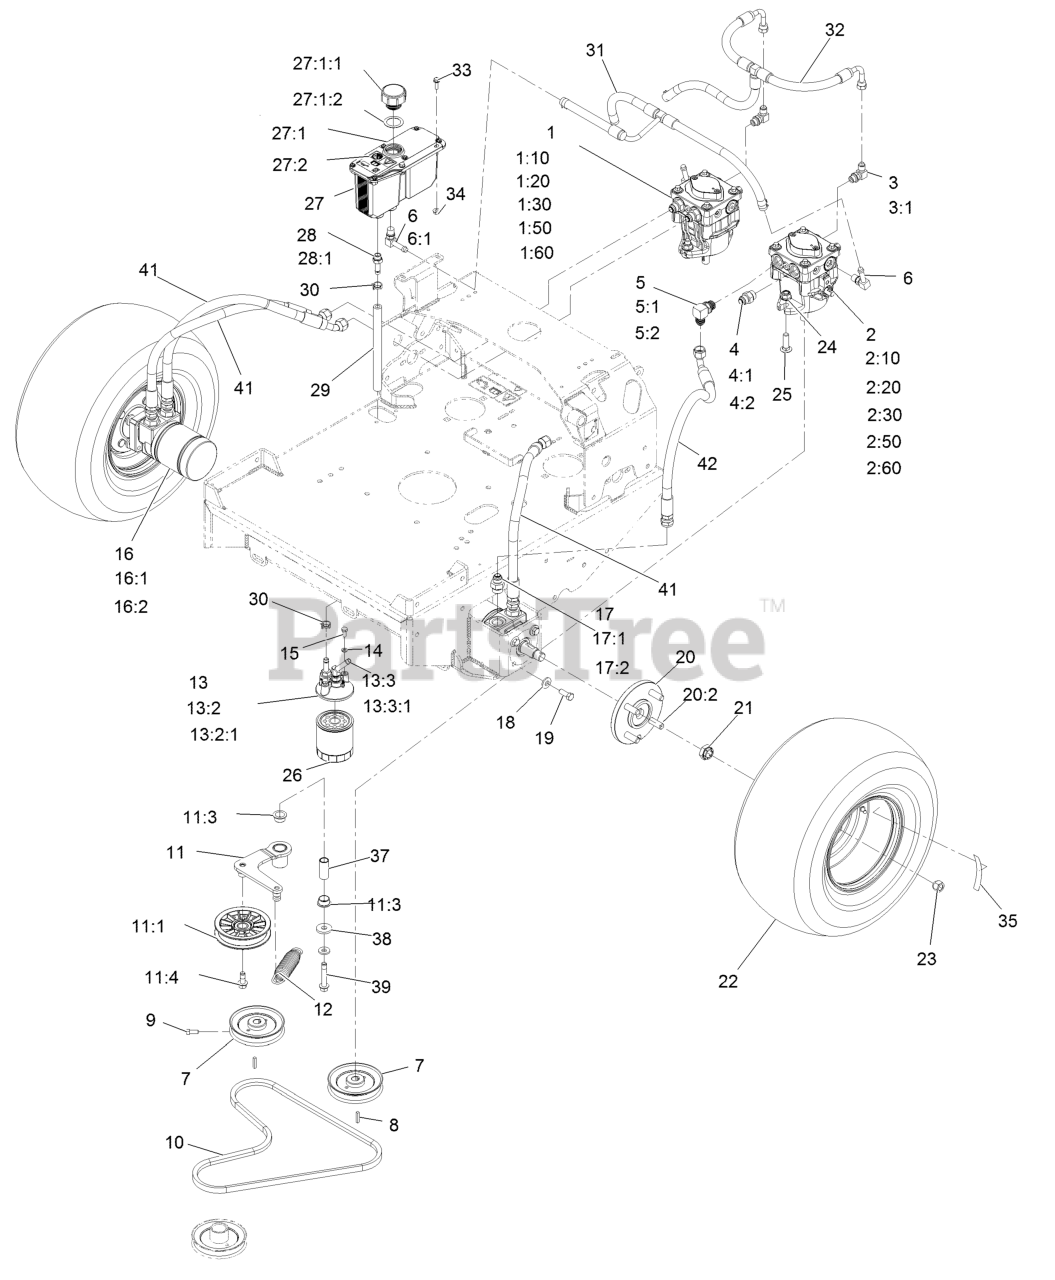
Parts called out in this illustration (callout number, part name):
1	PUMP-HYD PE RH TTH
1:10	INPUT SHAFT KIT
1:20	BEARING-THRUST
1:30	CYLINDER BLOCK KIT
1:50	SEAL OVERHAUL KIT
1:60	KIT, 10CC PUMP KIT
2	PUMP-HYD PE LH TTH
2:10	INPUT SHAFT KIT
2:20	BEARING-THRUST
2:30	CYLINDER BLOCK KIT
2:50	SEAL OVERHAUL KIT
2:60	KIT, 10CC PUMP KIT
3	FITTING-ELBOW, 90 DEG
4	FITTING-STRAIGHT
5	FITTING-90 DEG
6	FITTING-ELBOW, 90
6:1	O-RING
7	SHEAVE ASM
9	SCREW-SET, SQH
10	BELT
11	ASM, PUMP IDLER
11:1	PULLEY-IDLER, FLAT
11:3	BUSHING-FLANGE
11:4	SCREW-HFH
12	SPRING-EXTENSION
13	ASM, FILTER HEAD
13:2	ADAPTER-STRAIGHT
13:2:1	O-RING
13:3	FITTING-BARBED, 45 DEG
13:3:1	O-RING
14	WASHER-LOCK
15	SCREW-HH
16	HYD MOTOR ASM
16:1	SEAL KIT
16:2	BEARING AND SEAL KIT
17	FITTING-STRAIGHT
17:1	O-RING
18	WASHER-BELLEVILLE
19	SCREW-HH
20	WHEEL HUB ASM
20:2	STUD-WHEEL
21	NUT-LOCK
22	ASM, DRIVE TIRE
23	NUT-LUG
24	NUT-HF, NI
25	SCREW-HH
26	FILTER-25 MICRON, BI-DIRE
27:1	Reservoir-HYD
27:1:1	Cap-Reservoir, HYD
27:1:2	GASKET-CAP
27:2	DECAL-WARNING
28	ADAPTER-STRAIGHT
28:1	O-RING
29	HOSE,CASE DRAIN RH
30	CLAMP-HOSE
31	HOSE, CASE
32	HOSE, CHARGE
33	SCREW-HWH
35	DECAL-TORQUE WHEEL LUG-HU
37	PIVOT, IDLER
39	SCREW-HHF W/ PATCH
41	HOSE,HYDRAULIC W/COVER
42	HYD HOSE ASM
